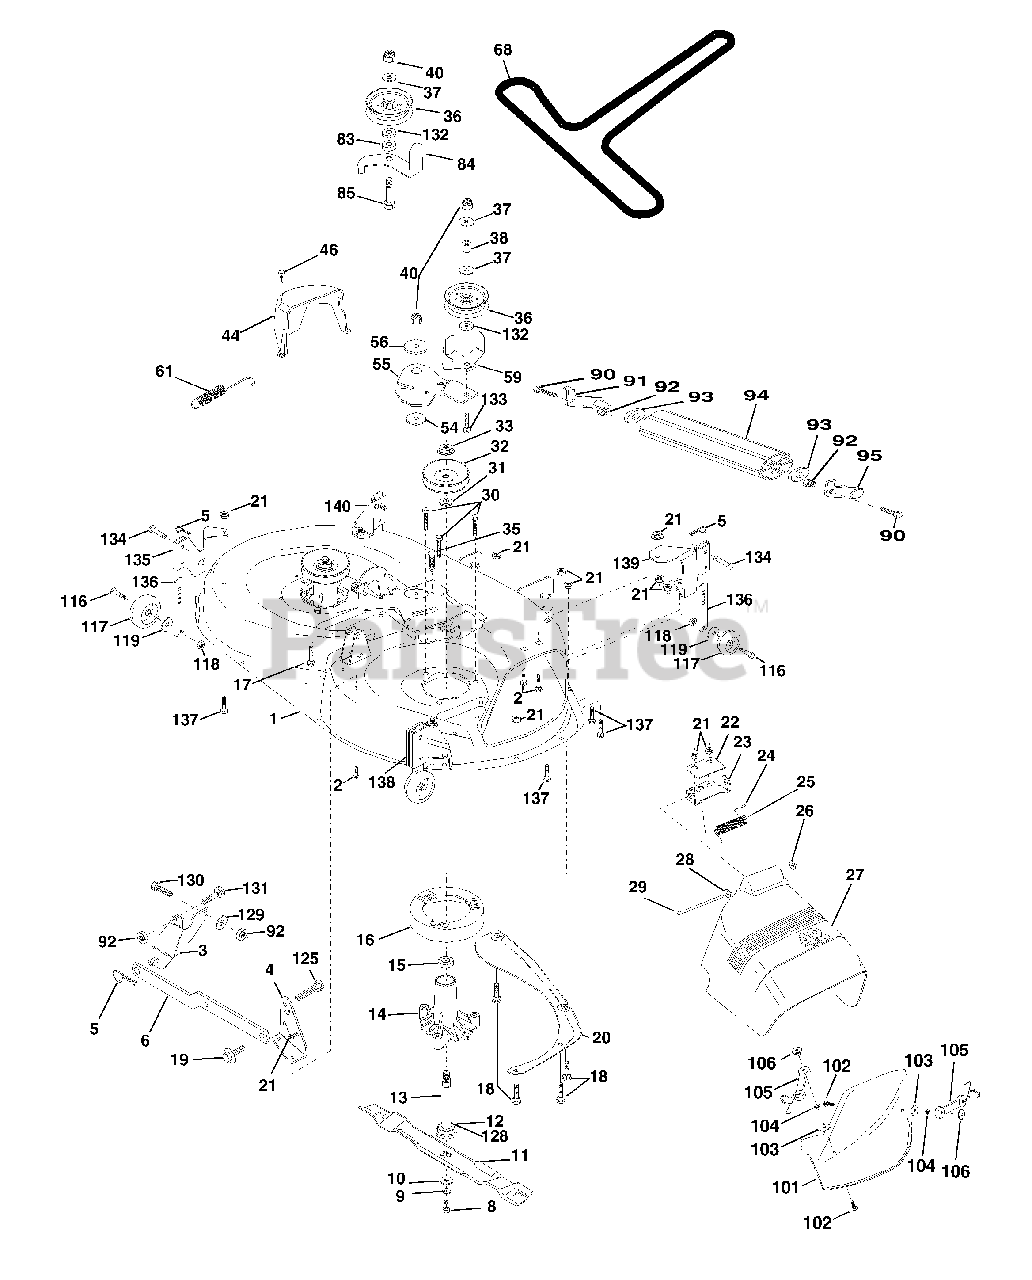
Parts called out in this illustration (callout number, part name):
1	Deck Weldment Mower 42" W/Adj
2	Bolt Rdhd Sqnk 5/16-18unc X3/4
3	Bracket Asm Fr Sway Bar 38/42
4	Bracket Asm Deck 42"sway Bar
5	Retainer Spring
6	Arm Suspension Rear
8	Bolt 3/8-24x1 25 Gr8 Patched
9	Washer Lock Hvy 3/8 Unplated
10	Washer Hard Blade Mower Vented
11	Blade Mower Mulching 42"
12	Bearing Ball #6204 (Mandrel)
13	Shaft Asm W/lower Bearing
14	Housing Mandrel Vented(machd)
15	Bearing Ball Mandrel
16	Stripper Round Mower
17	Bolt Rdhd Sqnk 3/8-16 X 2-1/4
18	Bolt Carr 5/16-18 X 5/8
19	Bolt Shoulder
20	Baffle Vortex 42
21	Nut Crown Lock 5/16-18
22	Stiffener Bracket 42"deck
23	Bracket Deflector Mower 42"
24	Cap Sleeve 80x 112 Blk Mower
25	Spring Torsion Deflector 2 52
26	Nut Push Phos & Oil
27	Shield Deflector Mower 42" Blk
28	Washer 11/32 X 5/8 X 16 Ga
29	Rod Hinge 42"6 75 Wlg
30	Screw Thdrol Washer Head
31	Washer Spacer Mower Vented
32	Pulley Mandrel 42"
33	Nut 9/16top Lock Flng Cntr
35	Fastner Christmas Tree
36	Pulley Idler Flat 3 060
37	Washer 13/32 X 13/16 X 16 Ga
38	Spacer Spring Stop Idler
40	Nut Lock 3/8-16 Unc
44	Guard Mandrel LH Black
46	Screw Thdrol 1/4-20x5/8
54	Washer Hardened
55	Arm Idler 42"mower LT/YT
56	Spacer Retainer Pm Mower
59	Guard, Belt
61	Spring Ext. Elect
68	V-Belt Mower
83	Washer Sintered
84	Keeper Belt Idler
85	Bolt Carriage 3/8-16 x 2-1/2 Gr.5
90	Bolt Fin Hex 3/8-16unc X 1
91	Bracket Asm Noseroller LH
92	Nut Lock Hex w/ins. 3/8-16 UNC
93	Washer 17/32 X 7/8 X 16 Ga
94	Roller Nose 38 & 42
95	Bracket Asm Noseroller RH
101	Cover Mulching 42" Blk
102	Screw
103	Washer #10
104	Washer Lock #10
105	Latch Asm Bagger
106	Nut Weld .327/.304 #10-24
116	Bolt Shld
117	Wheel Gauge blk.
118	Nut Centerlock 3/8 - 16 UNC
119	Washer 3/8 x 7/8 x 14 Ga.
125	Cotter Pin
128	Washer Felt
129	Washer 13/32 x 13/16 x 12 Ga.
130	Bolt Fin Hex 3/8-16 UNC x 1 Gr. 5
131	Bolt Rdhd Sqnk 3/8-16 Unc x 1
132	Washer 13/32 x 1-3/8 x 3 Ga
133	Bolt Rdhd 3/8-16 UNC x 2-3/4 Gr.5
134	Pin Head Rivet
135	Bracket Asm Whl Ga Rear LH 42"
136	Bar Pnt Adjusting Wheel Gauge
137	Bolt Carr 5/16-18 x 5/8 Short
138	Bracket Asm Whl Ga. Rear RH 42"
139	Bracket Asm Whl Ga. Front RH 42"
140	Bracket Asm Whl Ga. Front RH 42"
